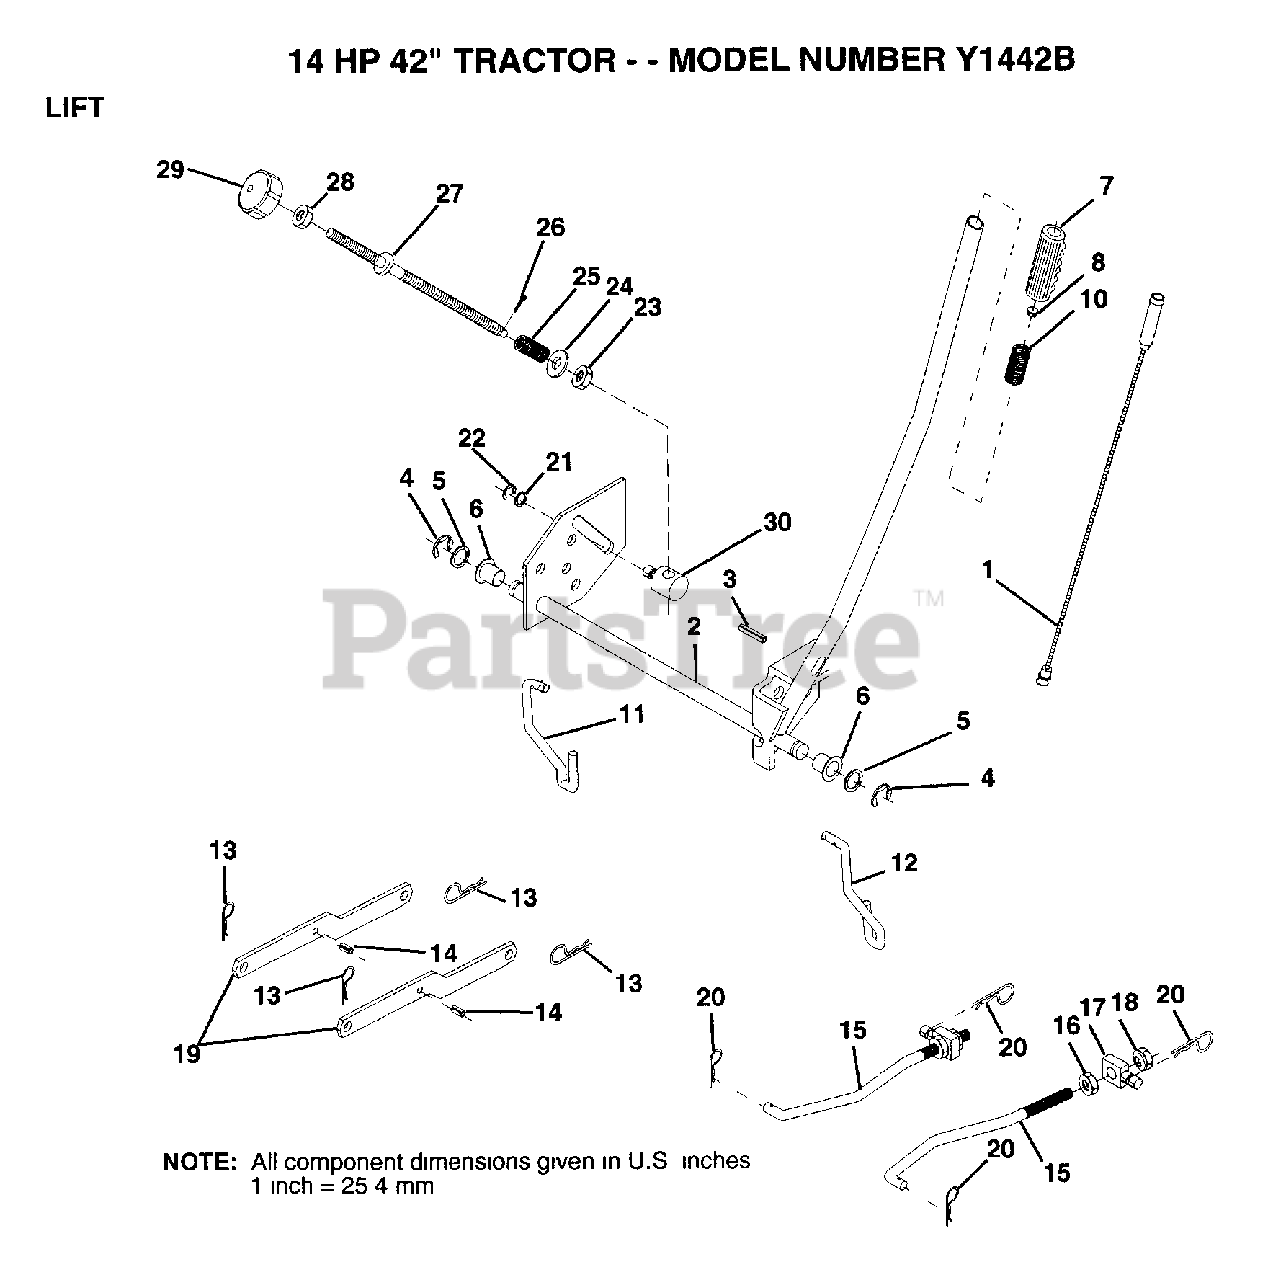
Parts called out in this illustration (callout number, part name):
1	WIRE ASM
3	PIN-GROOVE LT
5	WASHER
6	NYLON BEARING
7	GRIP
11	LINK LIFT LH
12	LIFT LINK RH
14	"PIN,SPRING"
15	LINK.FRONT
16	NUT
17	TRUNION
18	NUT.LK.W/WSH.1/2.
19	SUSP ARM ASM REAR
20	RETAINER.SPRING
21	WASHER
22	KLIP RING
23	NUT T
24	WASHER
25	SPRING T
28	NUT
29	KNOB INF 3/8-16
30	TRUNION LT
